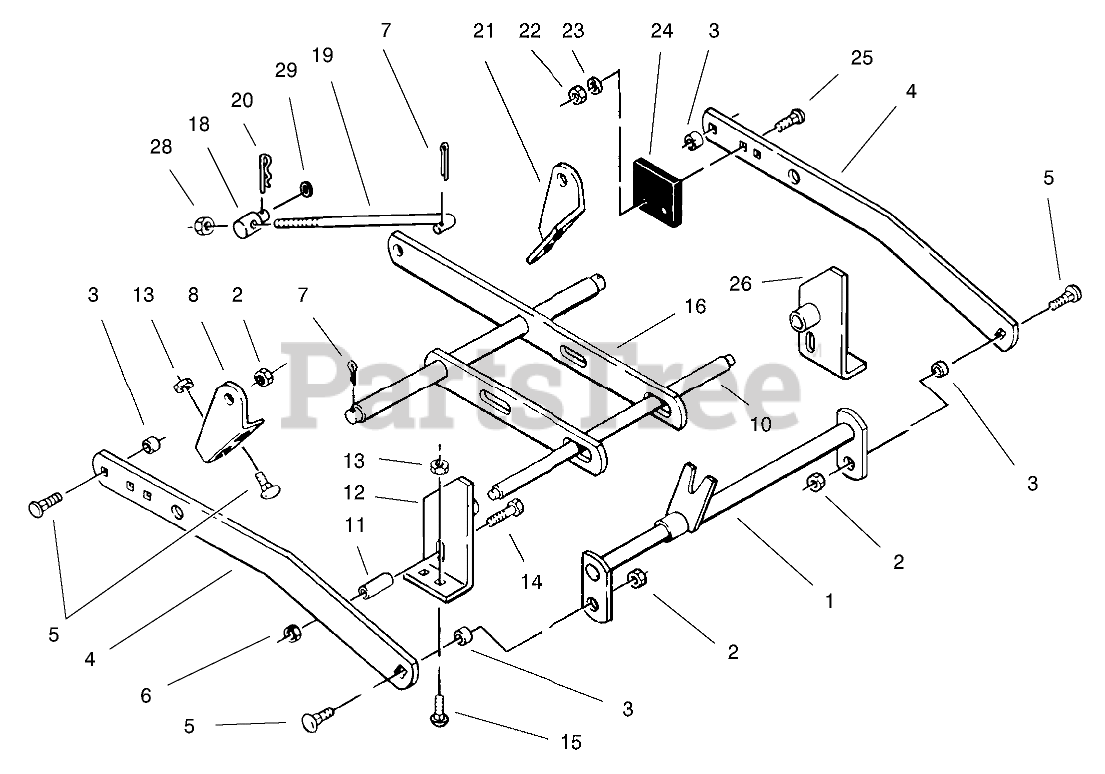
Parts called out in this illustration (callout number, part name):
1	WA HITCH (RED)
2	LOCKNUT-FLANGE
3	SPACER
4	BAR DRAFT (RED)
5	BOLT-CARR
6	NUT-LOCK, NI
7	PIN-COTTER
8	BRAKET-DCK R (RED)
10	SHAFT FRONT (RED)
11	SPACER
12	WA-RH FRT DK BRK (RED)
13	NUT-LOCK, NI
14	BOLT-CARR
15	BOLT-CARR
16	WA-LEVELER BAR (RED)
18	TRUNNION
19	LIFT ROD
20	PIN-HAIR
21	BRAKET-DCK L (RED)
22	NUT-LOCK, NI
23	WASHER-FLAT
24	BUMPER
25	SCREW-CARR
26	WA-LH FRT DK BRK (RED)
28	NUT-LOCK, NI
29	WASHER-FLAT
